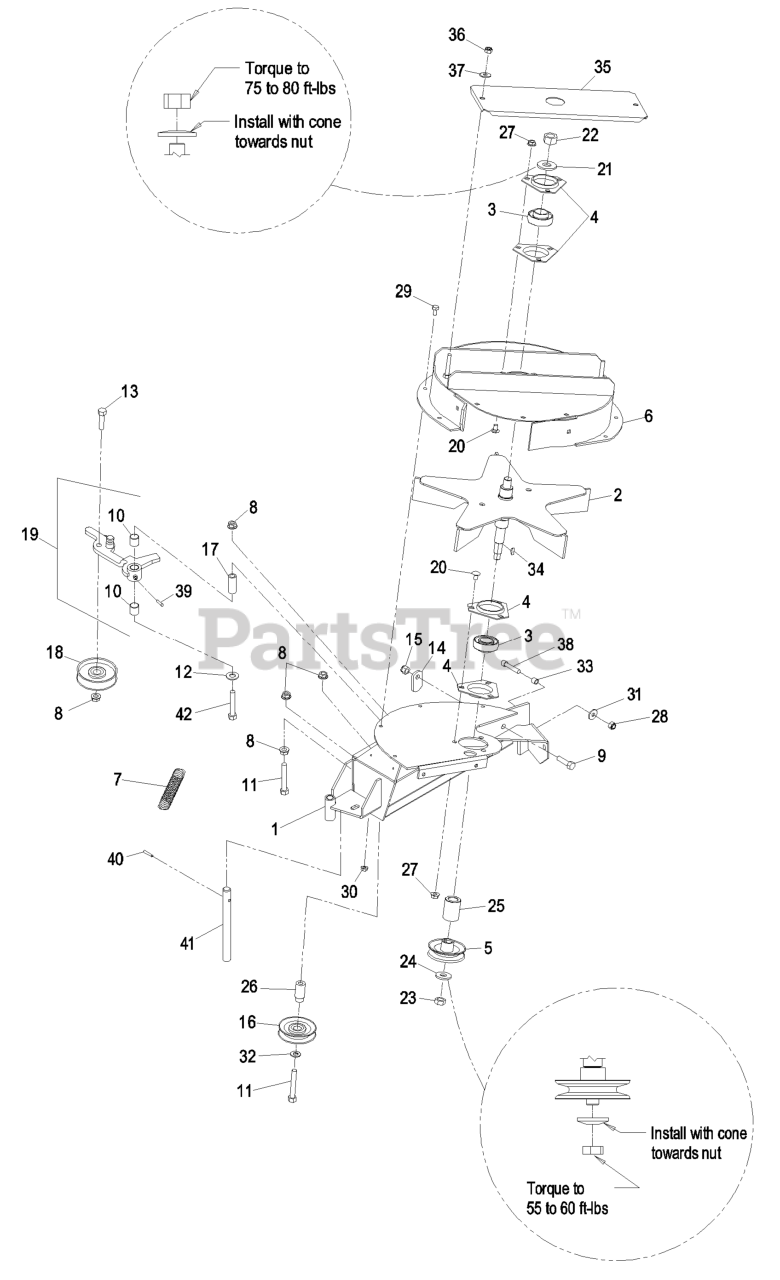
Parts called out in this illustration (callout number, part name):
1	WLD, BLOWER MOUNT
2	IMPELLER
3	BEARING
4	HOUSING-FLANGE
5	SHEAVE-BLOWER
6	ASM,UPPER HOUSING
7	SPRING-IDLER
8	NUT-HHF, WHIZ
9	SCREW-HH
10	BUSHING
11	BOLT-CARR
12	WASHER-FLAT
13	SCREW-HH
14	LATCH-CATCHER, GRASS
15	NUT-LOCK, NI
16	IDLER-INSIDE
17	BUSHING-PIVOT, IDLER
18	IDLER-FLAT
19	ASM, IDLER ARM - SERVICE
20	SCREW-CARR
21	WASHER-SPRING
22	NUT-HEX
23	NUT-JAM
24	WASHER-SPRING
28	NUT-HEX
29	SCREW-HH
31	WASHER-SPRING
32	WASHER-FLAT
33	BUSHING, LOCATOR
34	KEY-WOODRUFF
35	ASM, BEARING COVER
36	NUT-LOCK, NI
37	WASHER-FLAT
38	SCREW-HSH
39	FITTING-GREASE
40	PIN-ROLL
41	SHAFT-CATCHER, GRASS
42	SCREW-HSBH
